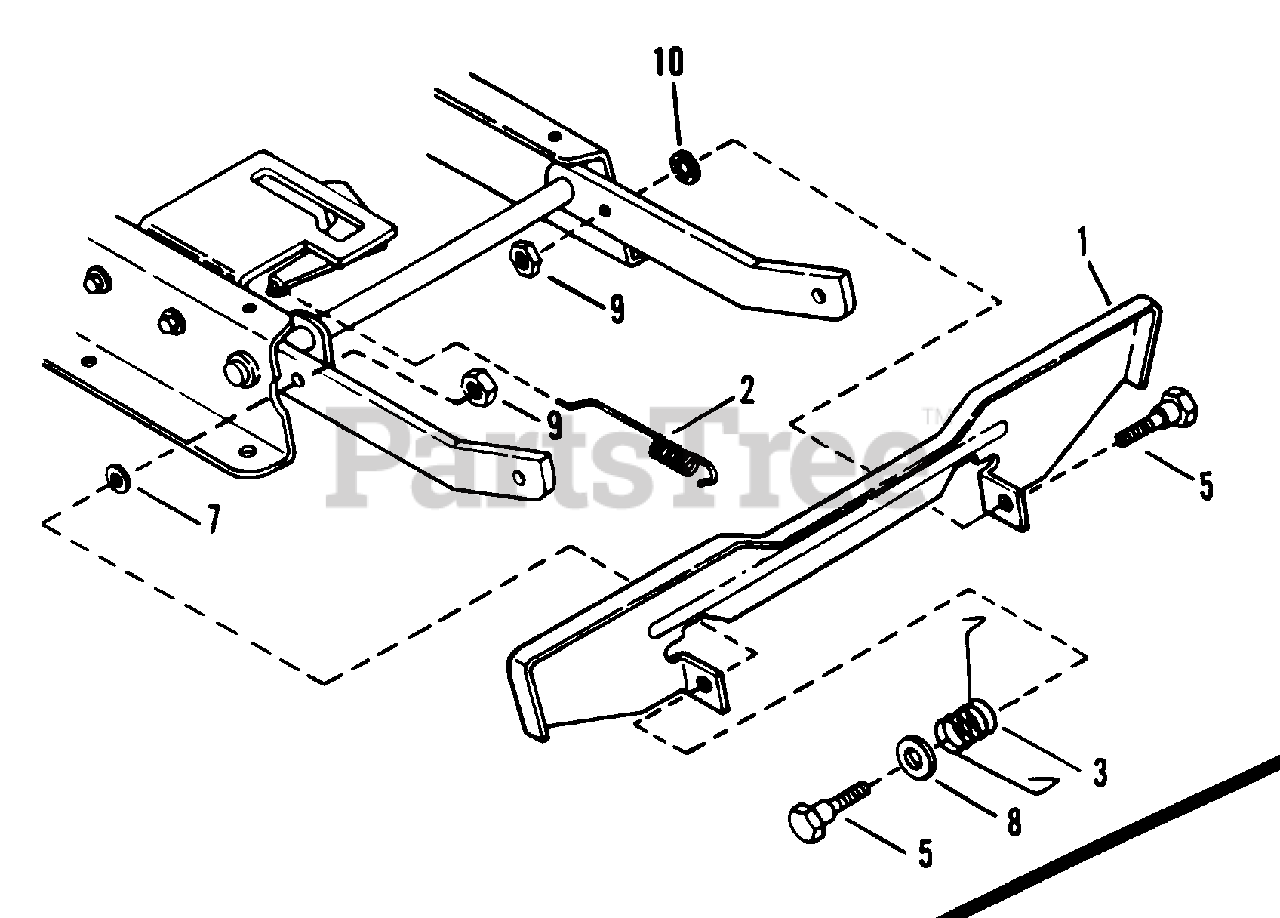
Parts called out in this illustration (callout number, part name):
1	PEDAL, Blade Stop Control
2	SPRING, Latching
3	SPRING, Pedal
5	BOLT, 3/8-24 x 9/16" Shoulder
7	WASHER, 3/8" Flat
8	WASHER, 1/2 Flat
9	NUT, 3/8-24 Hex Lock
10	WASHER, 3/8 Internal Tooth Lock
